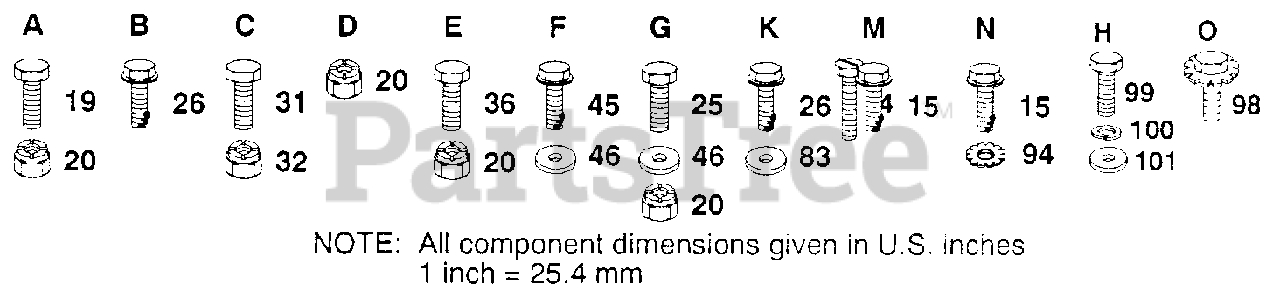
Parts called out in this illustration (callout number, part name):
4	LOCKWASHER
15	SCREW
19	BOLT
25	BOLT
26	SCREW
31	BOLT
45	SCREW
46	WASHER
94	LOCKWASHER
99	BOLT
100	LOCKWASHER
101	WASHER
